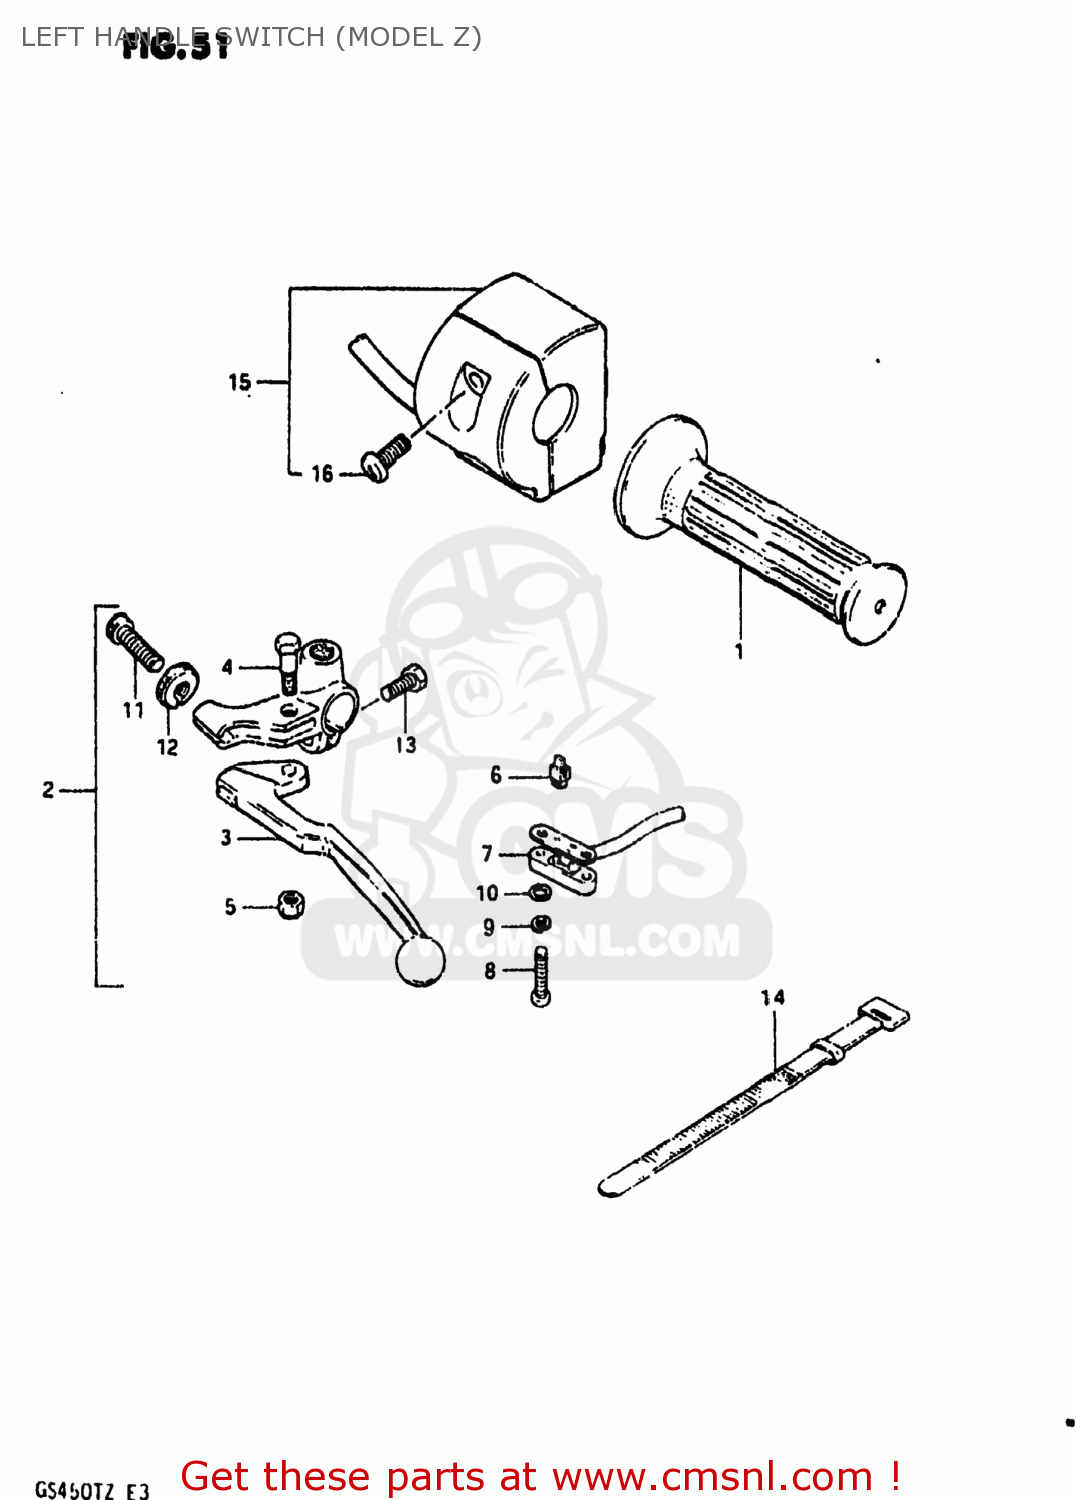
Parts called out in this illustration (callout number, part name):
1	GRIP,LEFT
2	LEVER ASSEMBLY
3	LEVER,CLUTCH
4	BOLT,LEVER
5	NUT 6MM
6	CONTACT,SWITCH
7	COVER,FR BK TERMINAL BASE
8	SCREW
9	LOCK WASHER
10	WASHER
11	ADJUSTER,CABLE
12	NUT,CABLE ADJUSTER
13	BOLT,CLUTCH LEVER HOLDER
14	CLAMP(L:120)
15	SWITCH ASSEMBLY,HANDLE,LEFT
16	SCREW
